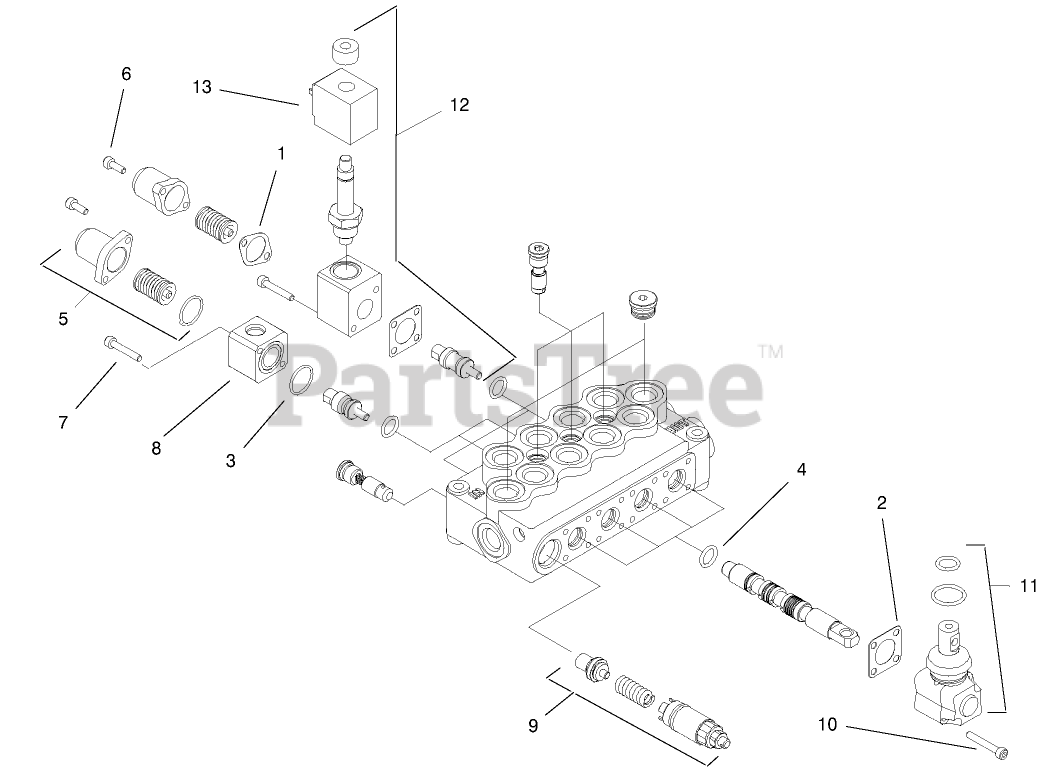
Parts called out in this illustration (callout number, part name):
1	GASKET
2	GASKET
5	STANDARD SPRING KIT
6	SCREW-CAP, END
8	BLOCK-MOUNT, SWITCH
9	VALVE-RELIEF
11	OPERATOR ASM
12	SPOOL LOCK ASM
13	COIL WITH CONNECTOR
